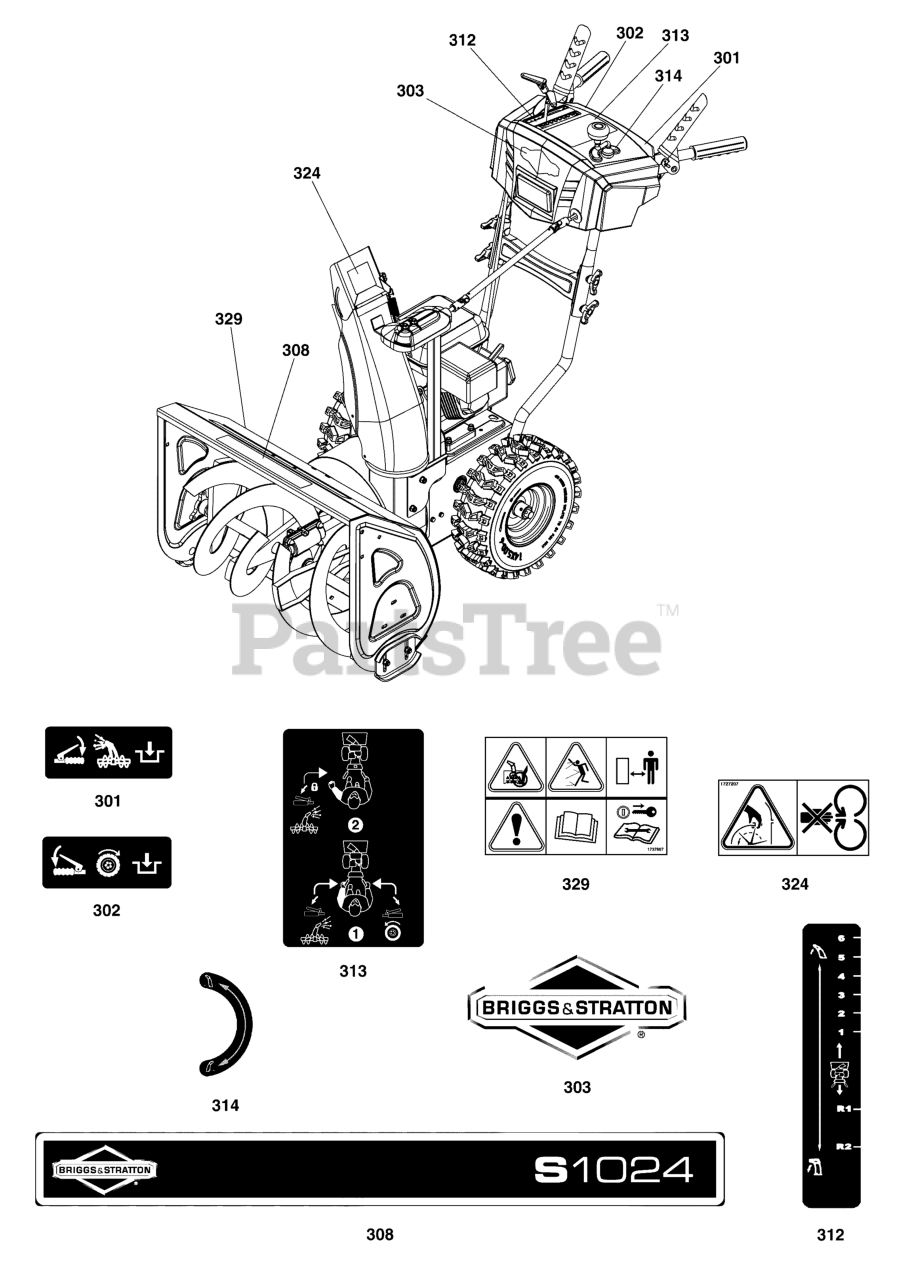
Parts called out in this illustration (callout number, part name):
1	KIT-DECAL, Briggs 1024MD
2	KIT-DECAL, Briggs 1024MD, Export
301	*DECAL, Auger Control
302	*DECAL, Traction Control
303	*DECAL, Control Panel, Briggs & Stratton
304	DECAL, Danger Chute
309	DECAL, Danger Foot
312	*DECAL, 1-5 Transmission Speed Control
313	*DECAL, Free Hand Operation
314	*DECAL, Chute Rotation
324	DECAL, Chute Warning, Export
329	DECAL, Danger Auger Icons, Export
